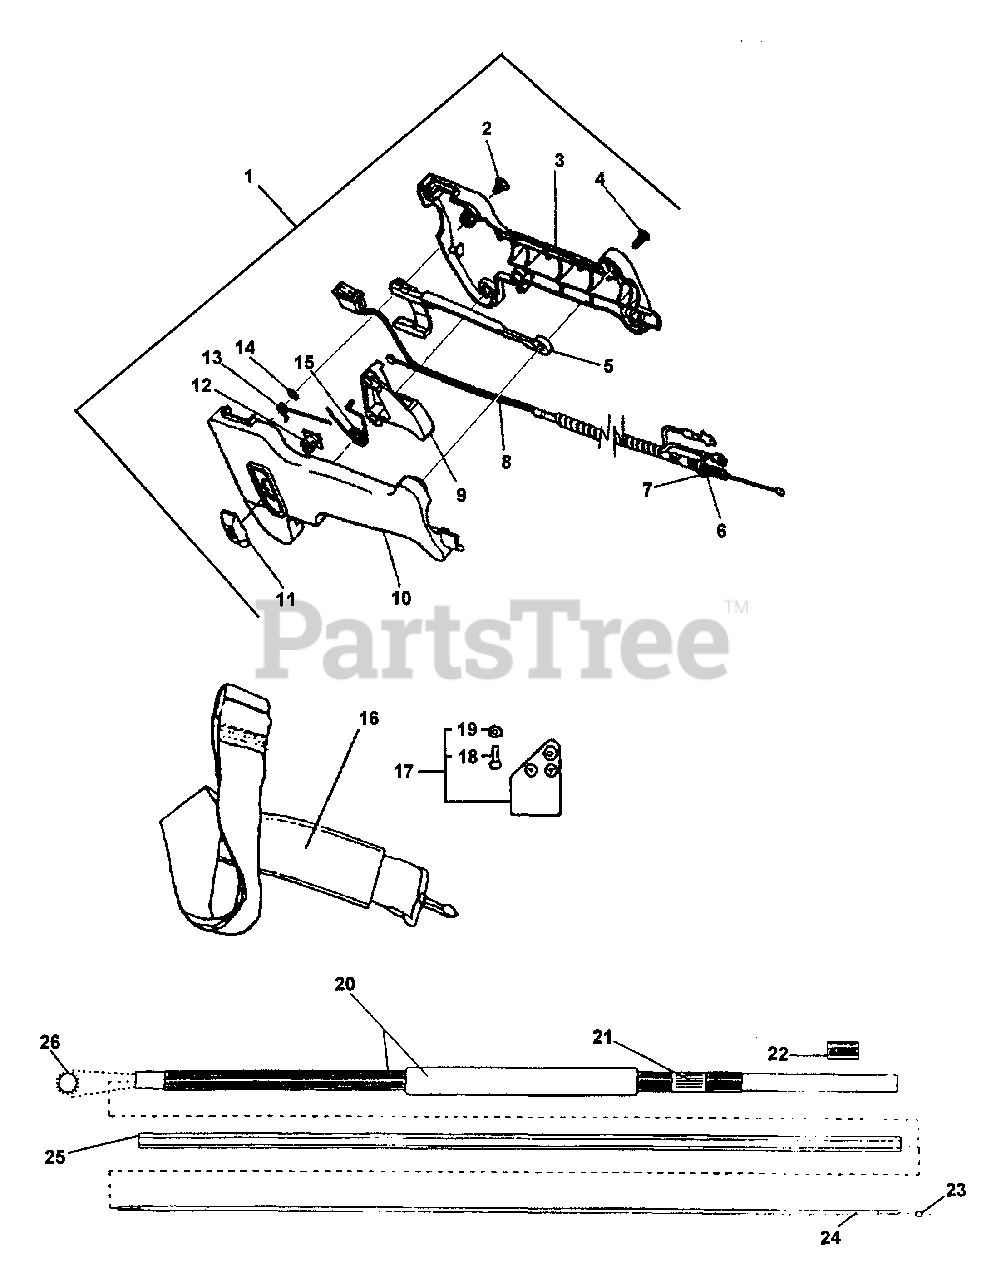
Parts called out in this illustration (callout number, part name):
1	CONTROL HANDLE ASSY
2	SCREW - 12 X 1/2"
3	HANDLE - RIGHT
4	SCREW
5	LOCKOUT, THROTTLE
6	WASHER - 6
7	NUT - 6
8	CONTROL CABLE ASSY
9	TRIGGER, THROTTLE
10	HANDLE, CONTROL - LEFT
11	SWITCH, THROTTLE
12	LOCKOUT, THROTTLE
13	SPRING, LOCKOUT LEVER
14	NUT, SPEED
15	SPRING, TRIGGER
16	SHOULDER STRAP ASSY
17	HANGER KIT
18	SCREW
19	LOCKNUT - 10-24
20	MAIN PIPE ASSY
21	LABEL - WARNING
22	SLEEVE, HOUSING 2-5/8"
23	LOCKWASHER - INTERNAL
24	DRIVESHAFT - FLEXIBLE
25	LINER - FLEXIBLE
26	LOCKWASHER - EXTERNAL
